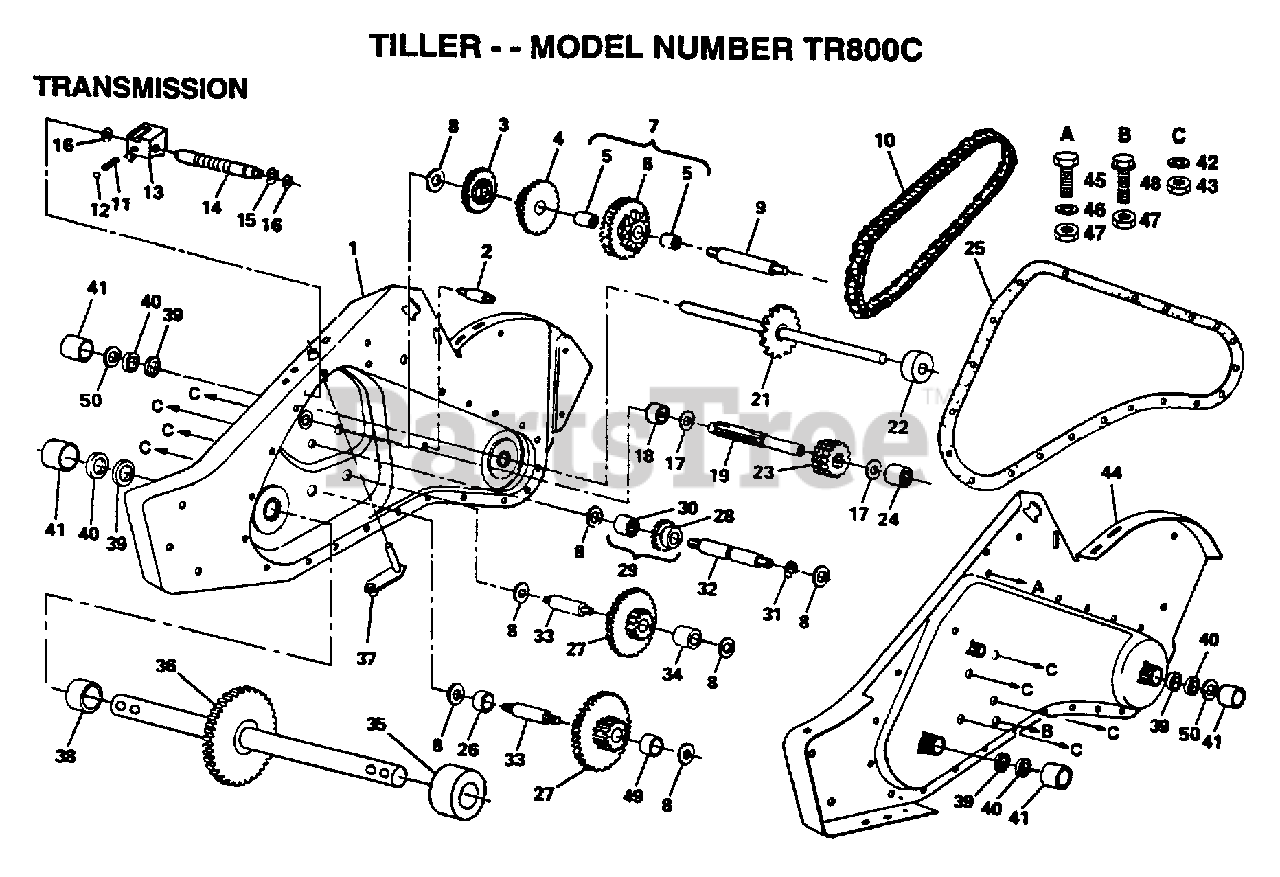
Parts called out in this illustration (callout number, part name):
2	BOLT TI
3	REVERSE GEAR TI
4	CLUSTER GEAR TI
5	"CRT, BEARING"
7	SPROCKET ASSY TI
8	WASHER
9	REDUCTION SHFT TI
10	CHAIN TI
11	SPRING-SHIFT CRT
13	SHIFT FORK TI
14	SHIFT SHAFT TI
15	KLIP RING
16	WASHER SEAL CRT
17	"T, BEARING"
18	"TI, BEARING"
19	SHAFT INPUT T
21	SHAFT TINE CRT
22	SPACER CRT
23	INPUT PINION TI
24	NEEDLE BRNG LT
25	GEARCASE GSKT TI
26	SPACER CRT
27	GEAR CLUSTER CRT
28	REVERSE GEAR TI
29	GEAR ASSY TI
30	NEEDLE BEARING TI
31	KLIP RING
32	REVERSE SHAFT TI
33	SHAFT CRT
34	SPACER CRT
35	SPACER CRT
36	SHAFT ASSY CRT
37	BRACKET ASM SHIFT
38	SPACER CRT
39	OIL SEAL STD
40	SEAL RING RUBBER
41	CUP.FORMED.
42	LOCKWASHER
43	NUT.ASF.HEX.7/16
45	BOLT
46	LOCKWASHER
47	NUT.HEX.5/16-18
48	BOLT TI
49	SPACER CRT
50	RING SPIRAL CRT
